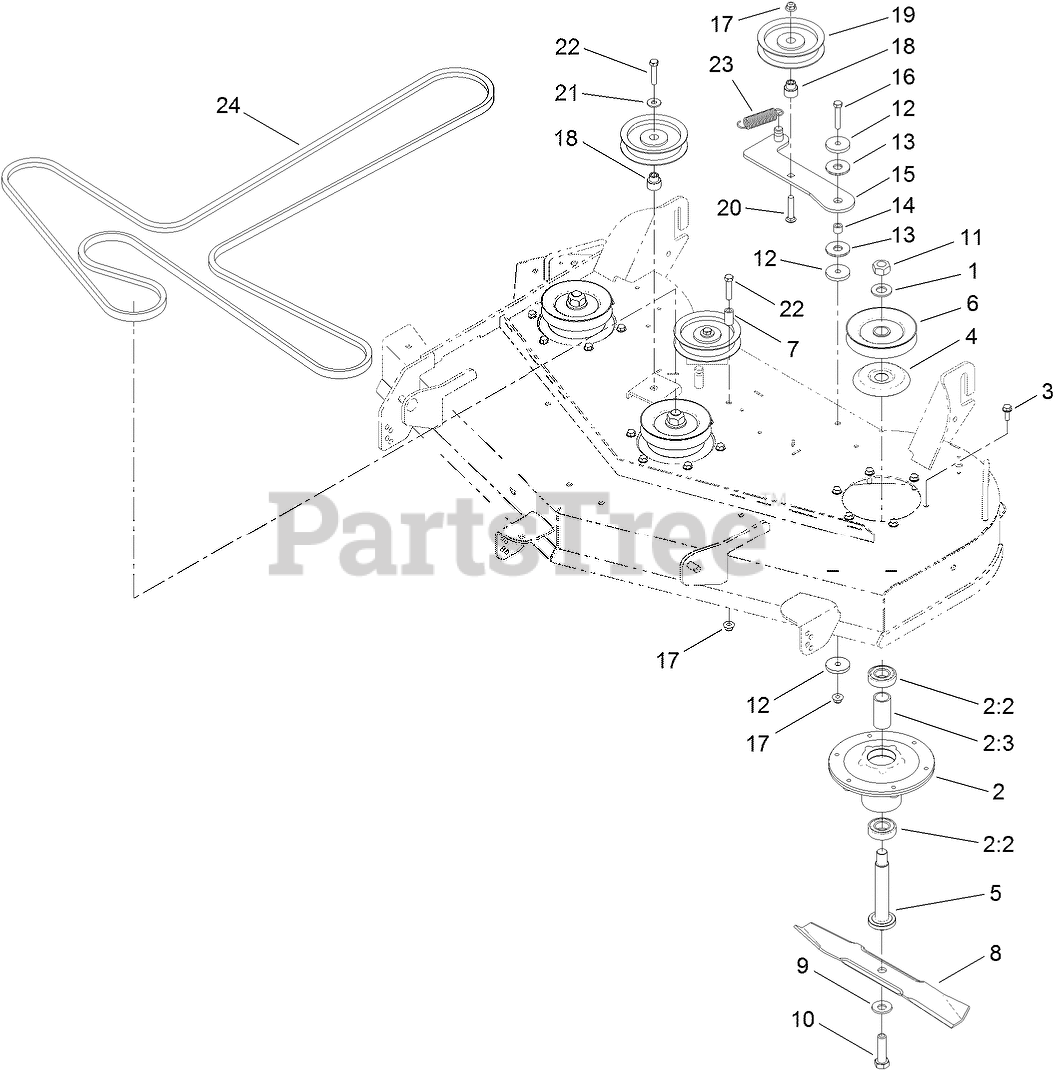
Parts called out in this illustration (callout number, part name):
1	WASHER
2	SPINDLE ASM
2:2	BEARING-BALL
2:3	SPACER-BEARING
3	SCREW-TAPTITE
4	SHIELD-BEARING
5	SHAFT-SPINDLE
6	PULLEY
7	SPACER
8	BLADE-MULCH, 16.50 INCH
9	WASHER-BELLEVILLE
10	SCREW-BLADE
11	NUT-HEX
12	WASHER-PLAIN
13	WASHER-FRICTION, COMPOSITE
14	BUSHING-LEVER, LIFT
15	ARM-IDLER
16	SCREW-HH
17	NUT-HF, NI
18	BUSHING-IDLER
19	PULLEY-IDLER
20	SCREW-CARR
21	WASHER-HARDENED
22	SCREW-HH
23	SPRING-EXTENSION
24	V-BELT
